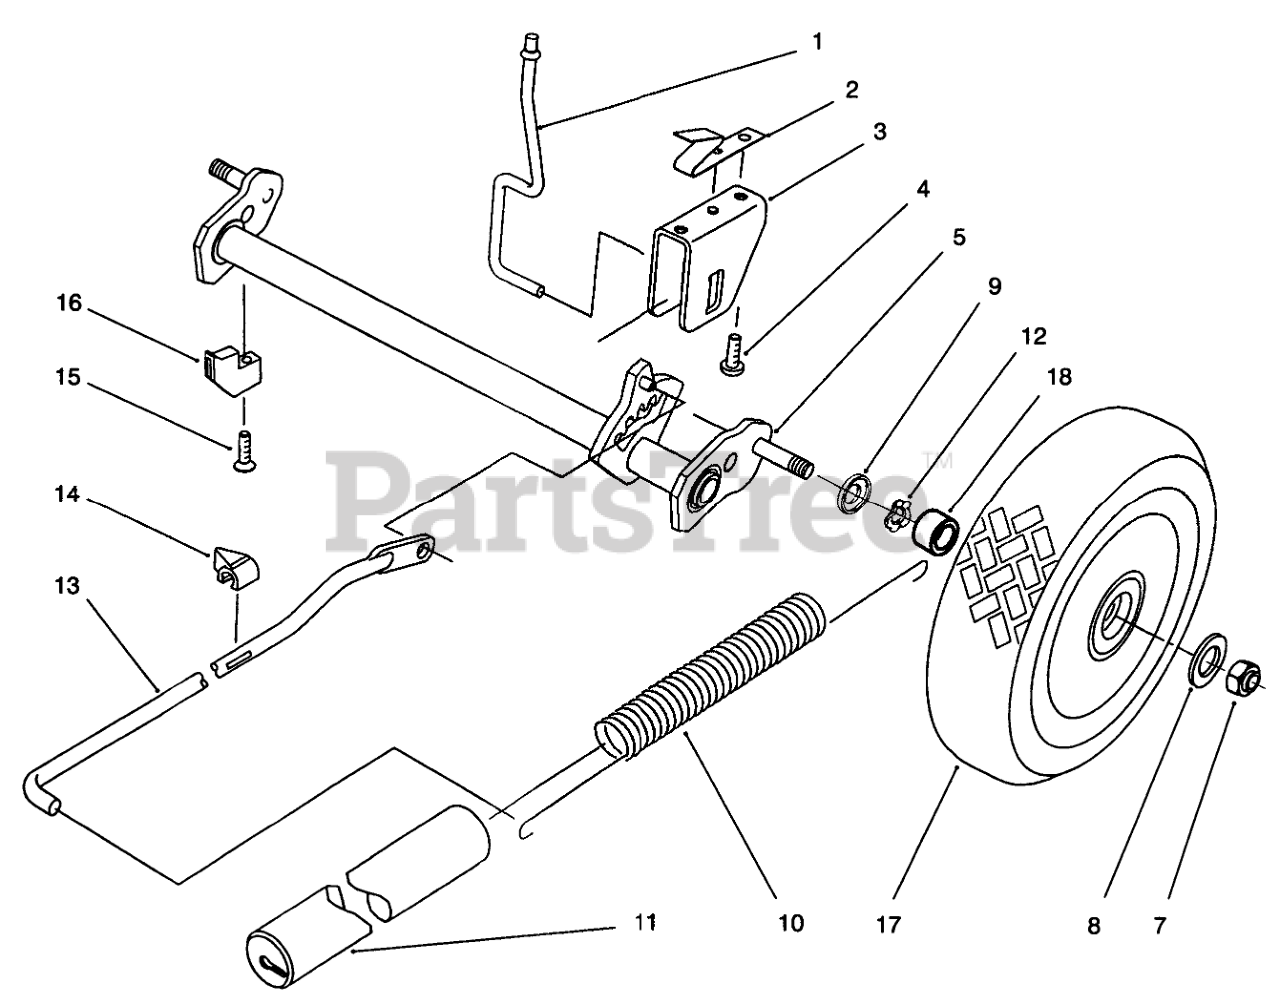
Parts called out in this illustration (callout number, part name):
1	Rod-Trigger
2	SPRING-RETURN, TRIGGER
3	SADDLE-HEIGHT OF CUT
4	SCREW-RH
5	AXLE-REAR
7	NUT-HH
8	WASHER-WHEEL
9	CAP-AXLE, REAR
10	SPRING-COUNTERBALANCE
11	COVER-SPRING
12	WASHER-WAVE
13	ROD-LINK
14	INDICATOR-HEIGHT OF CUT
15	SCREW-RETAINER
16	RETAINER - AXLE
17	WHEEL-SMART, REAR
18	BUSHING
